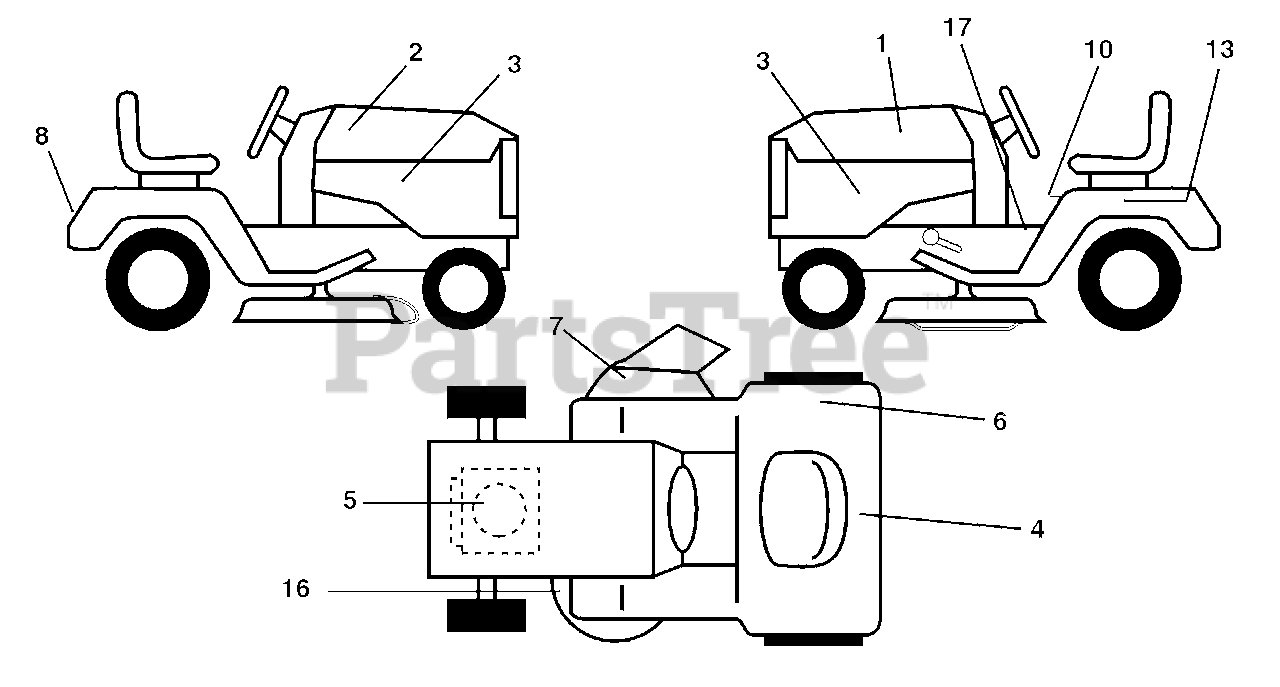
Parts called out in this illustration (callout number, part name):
1	Decal, Hood, L. H.
2	Decal, Hood, R. H.
3	Decal, Pnl Side
4	Decal, Tick Mark Australia
5	Decal, Engine
6	Decal, DBA
7	Decal, Warning Multi/Lang
8	Decal, Logo, Fender
10	Decal Caution Fender
13	Decal, Caution, Battery
16	Decal, V-Belt Sch.
17	Decal, Inst. Oper.
